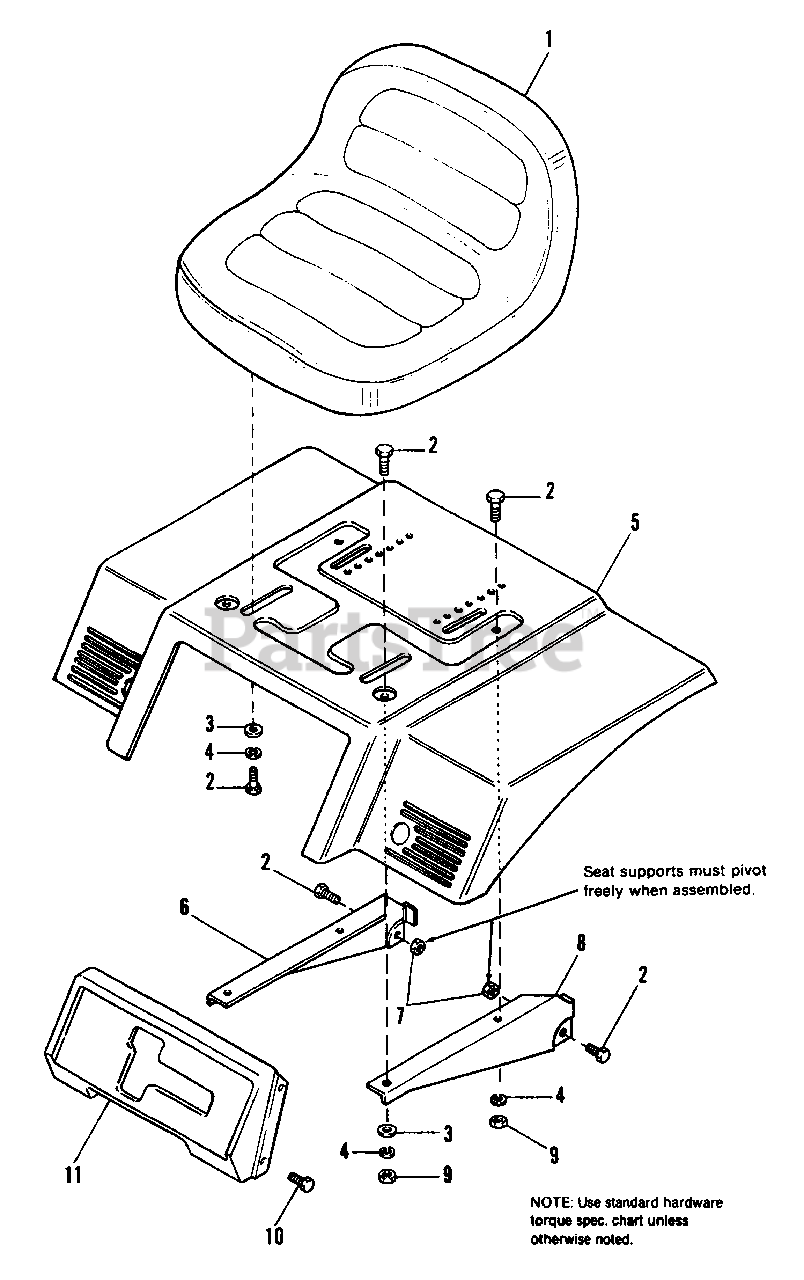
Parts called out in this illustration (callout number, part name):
2	CAPSCREW, 5/16-18 x 3/4
3	WASHER, 5/16
4	LOCKWASHER, 5/16
5	DECK, Seat
6	SUPPORT, Seat, R.H.
7	NUT, Hex, 5/16-18
8	SUPPORT, Seat, L.H.
9	NUT, Hex, 5/16-18
10	SCREW, Taptite, 1/4-20 x 1/2
11	PANEL, Shift
